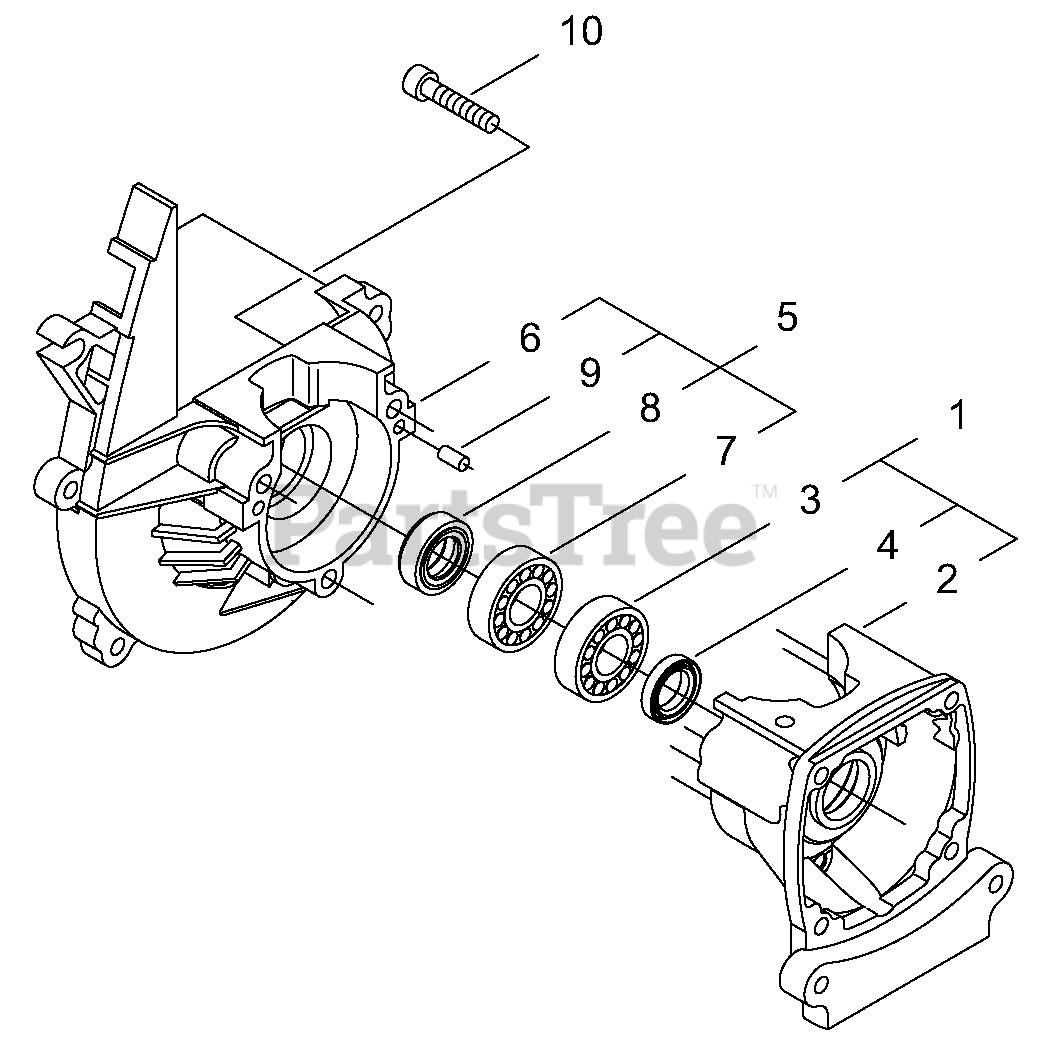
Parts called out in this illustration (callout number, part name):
1	CRANKCASE ASSY, S
2	CRANKCASE S
3	BEARING, BALL
4	SEAL, OIL 12
5	CRANKCASE ASSY, M
6	CRANKCASE M
7	BEARING, BALL
8	SEAL, OIL 12
9	PIN, LOCATING Ø4×8
10	BOLT 5×25
11	COVER ASSY, FAN
12	COVER, FAN
13	BEARING, BALL 6000ZZ
14	RING, SNAP Ø26
15	DRUM, CLUTCH
16	RING, SNAP WR10
17	CUSHION
18	BOLT M5×16
19	BOLT M5×45
20	COVER ASSY, ENGINE
21	COVER, ENGINE
22	THUMBSCREW
23	INSULATOR 5 MM
24	CLIP
25	WASHER, CONE M6
26	CUSHION, AV
27	CUSHION, FRONT
28	HOLDER, REAR CUSHION
29	BOLT M5×25
30	COVER, AV CUSHION (RED)
31	BOLT M5×16
